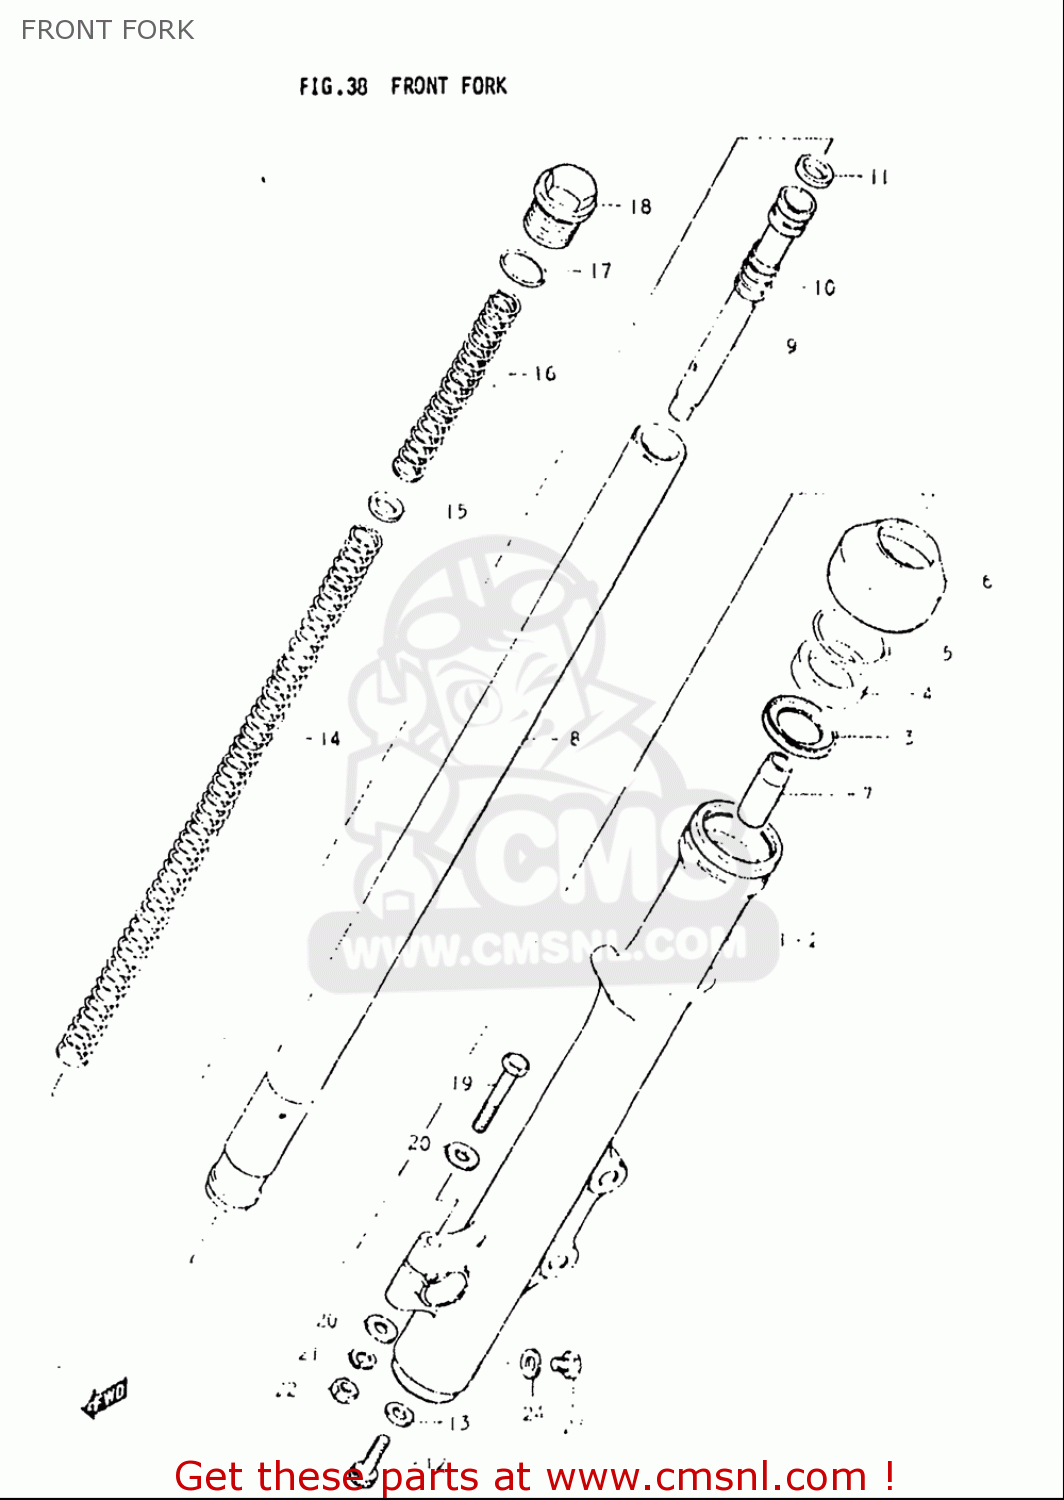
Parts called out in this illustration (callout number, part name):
3	SPACER,SEAL
4	SEAL,OIL 35X48X11
5	RING,OIL SEAL STOPPER
6	DUST SEAL,FR FORK
7	PIECE,OIL LOCK
11	RING
12	BOLT(8X27)
13	GASKET (NAS)
15	WASHER,SPRING
17	O RING
18	CAP,INNER TUBE
19	BOLT
20	WASHER
21	WASHER,LOCK
22	NUT
23	BOLT
24	GASKET,DRAIN,PLUG (NAS)
